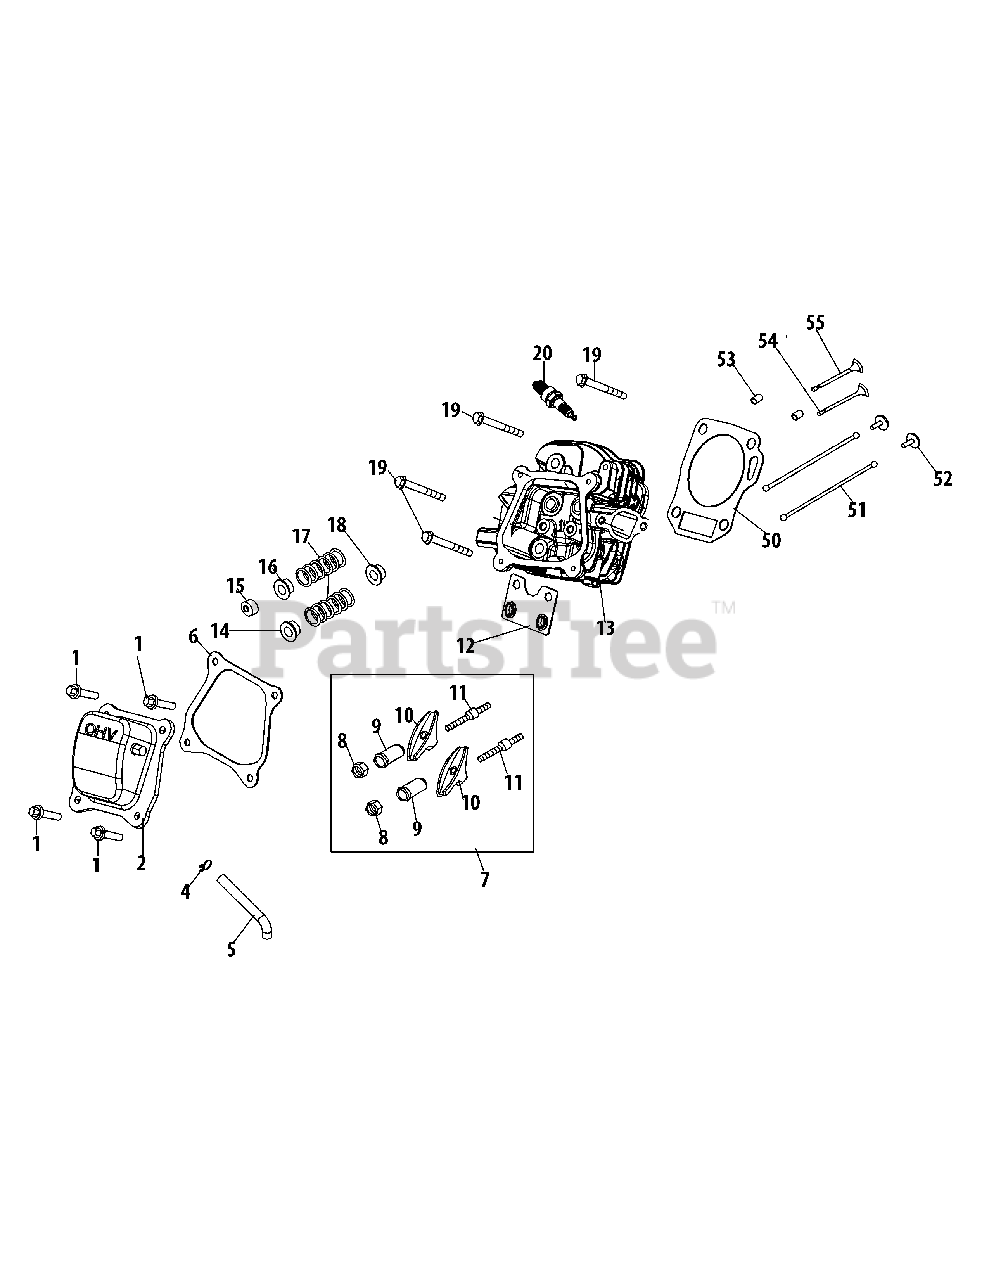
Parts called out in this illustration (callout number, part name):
1	Bolt M6×16
2	Cylinder Head Cover
4	Clamp, Vent Hose
5	Venting Hose
6	Gasket, Valve Cover
7	Rocker Arm Assembly
10	Rocker Arm
11	Rocker Arm Stud
12	Rocker Arm Base
13	Cylinder Head
14	Intake Valve Spring Seat
15	Rotator,Exhaust Valve
16	Exhaust Valve Spring Seat
17	Spring Valve
18	Intake Valve Seal
19	Bolt M8×55
20	Spark Plug(F6Rtc)
50	Gasket,Cylinder Head
51	Push Rod
53	Dowel Pin 10×16
54	Valve Intake
55	Exhaust Vavle
